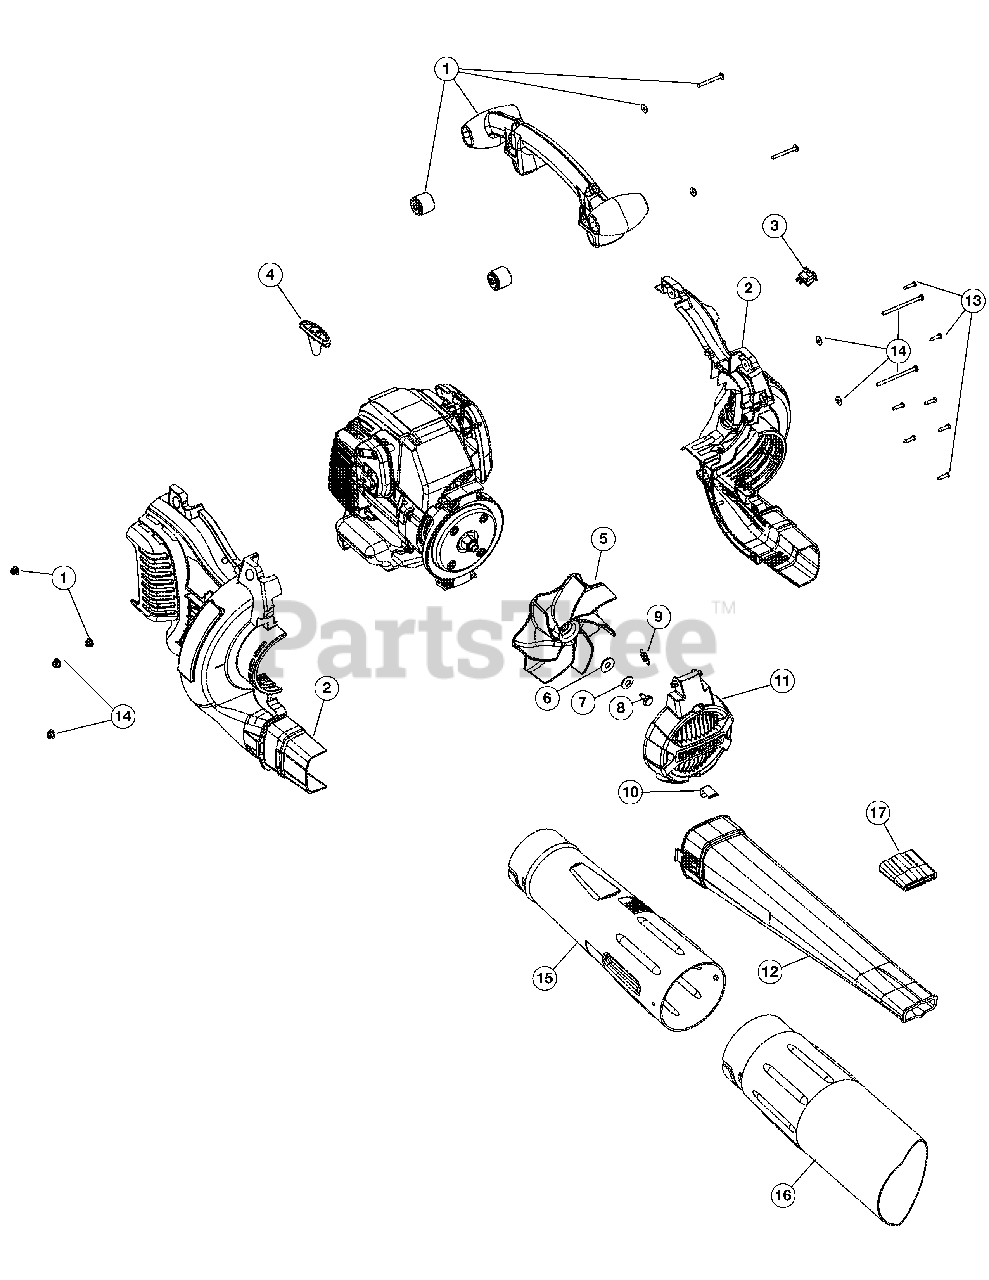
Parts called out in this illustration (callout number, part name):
1	Handle Assembly
2	Housing Assembly
4	Handle
5	Impeller
6	Washer
7	Washer
9	Spring
10	Clip
11	Vacuum Door
12	Blower Tube
14	Impeller Housing Hardware
15	Upper Vacuum Tube
16	Lower Vacuum Tube
17	Concentrator Nozzle
